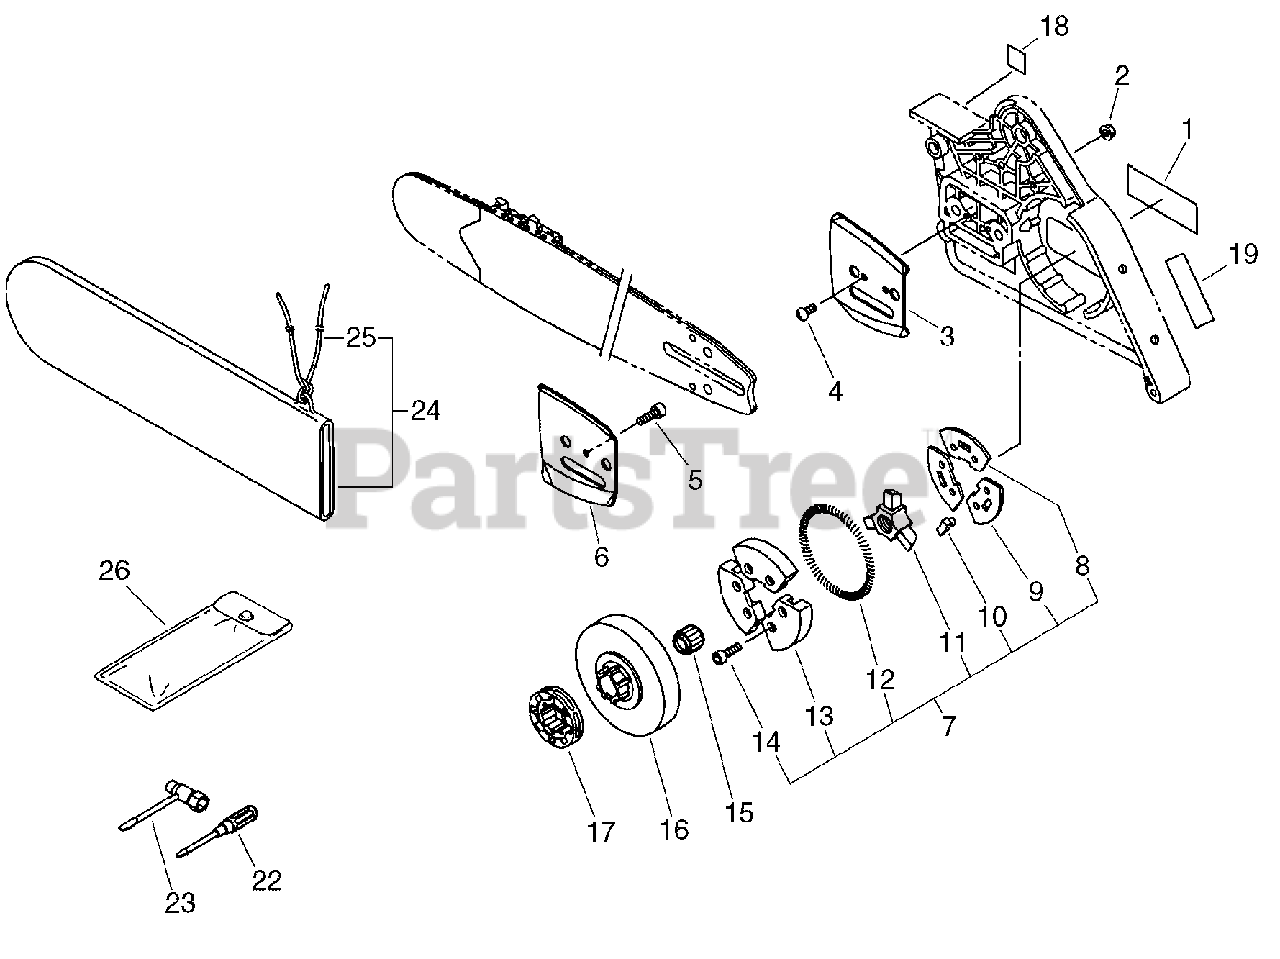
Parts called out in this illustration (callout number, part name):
1	LABEL - ECHO
2	NUT - 8 -- FLANGE
3	PLATE, GUIDE - OUTER
4	SCREW - 3X6
5	SCREW - 4X8
6	PLATE, GUIDE - INNER
7	CLUTCH ASSY
8	PLATE, CLUTCH
9	PLATE, CLUTCH
10	PLATE, SPRING
11	HUB, CLUTCH
12	SPRING, CLUTCH
13	CLUTCH SHOE SET
14	SCREW - 4X8
15	BEARING, NEEDLE
16	DRUM, CLUTCH
17	SPROCKET, RIM
18	LABEL - CAUTION
19	LABEL - CAUTION
22	SCREWDRIVER
23	T-WRENCH - 13X19mm
24	COVER, GUIDE BAR
26	BAG, TOOL
